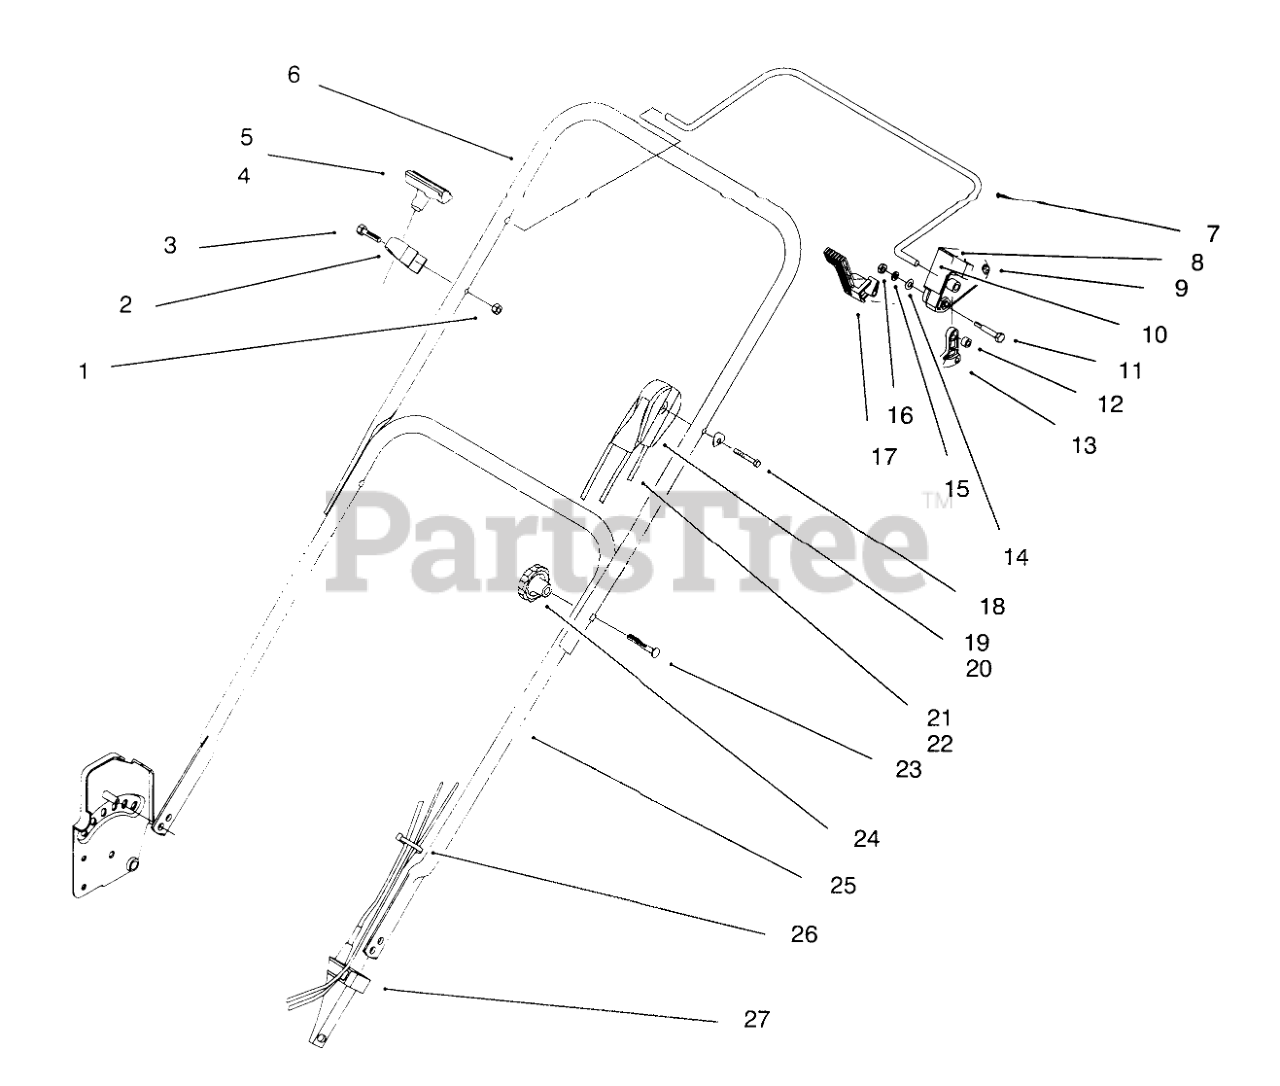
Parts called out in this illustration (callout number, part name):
1	NUT-LOCK, NI
2	GUIDE-ROPE
3	SCREW-HH
4	HANDLE-START
5	CLIP-STARTER
6	Handle-Upper
7	Bar-Control
8	DECAL - INSTRUCTION
9	STOP - PIVOT, PLASTIC
10	DECAL - INSTRUCTION
11	SHOULDER BOLT
12	SPACER-LEVER, TRACTION
13	LEVER-TRACTION
14	WASHER - SPRING
15	WASHER-PLAIN
16	NUT-LOCK, NI
17	LEVER - SHIFT
18	WASHER - CURVED
19	CABLE - THROTTLE/TRACTION (Model 20444 and 20454)
20	CABLE - THROTTLE/TRACTION (Model 20442 Only)
21	CABLE - BRAKE (Model 20444 and 20454)
22	CABLE - BRAKE (Model 20442 Only)
23	SCREW-HANDLE
25	Handle-Lower
26	TIE-CABLE
27	ANCHOR-CABLE
